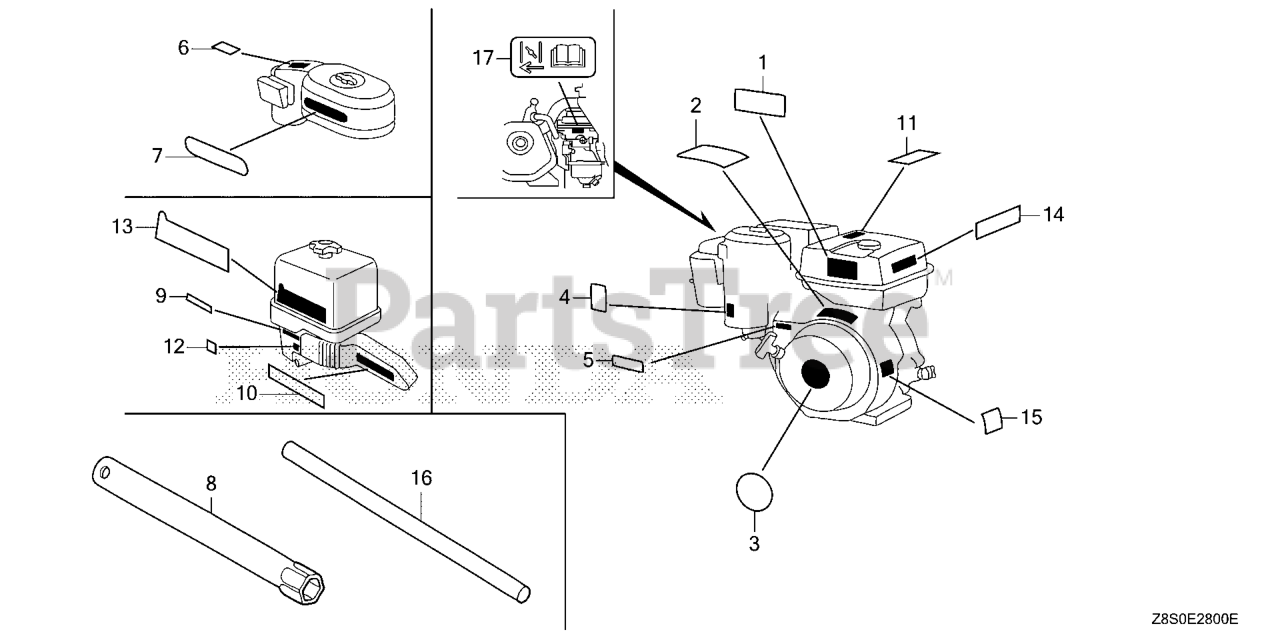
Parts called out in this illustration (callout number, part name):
3	EMBLEM (GX240)
4	MARK, CHOKE
5	MARK, THROTTLE INDICATION
8	WRENCH, SPARK PLUG
11	MARK, EX. CAUTION (ENGLISH)
14	MARK, OPERATOR CAUTION (ENGLISH)(MADE IN THAI)
14	MARK
